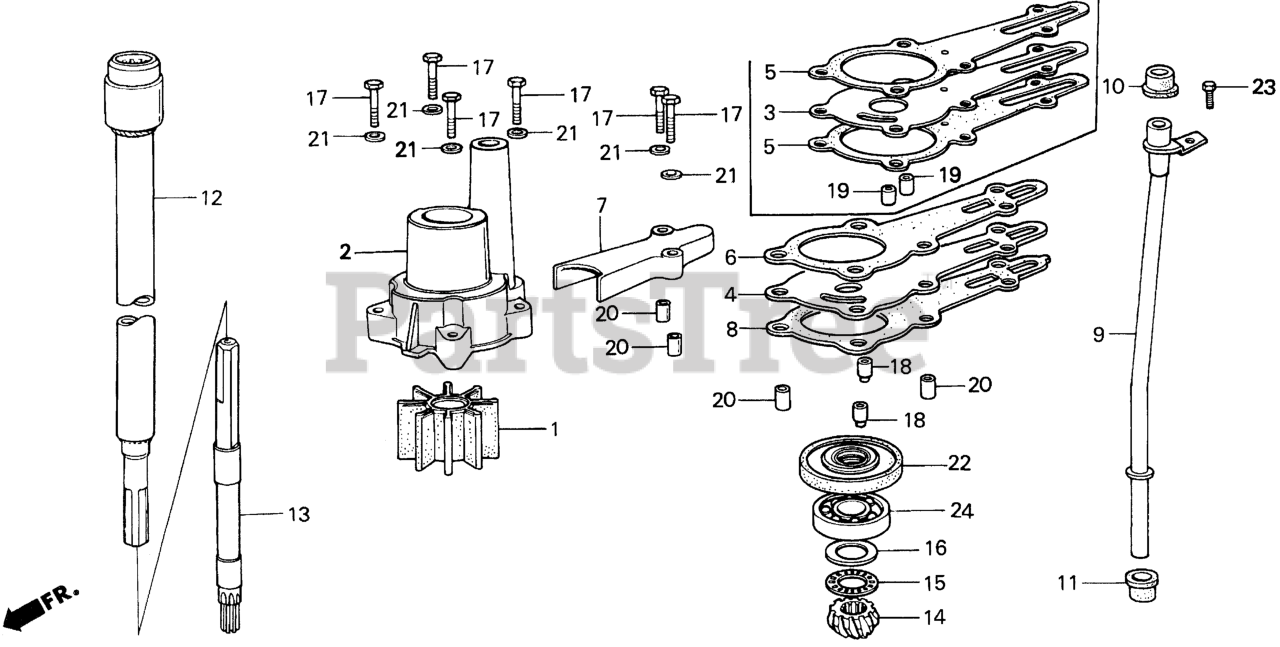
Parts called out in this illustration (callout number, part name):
1	IMPELLER, PUMP
2	HOUSING, IMPELLER
3	COVER, IMPELLER
5	GASKET, IMPELLER
7	HOLDER, IMPELLER COVER
9	TUBE, WATER (S)
10	RING, WATER TUBE SEAL
11	RING, SEAL
12	SHAFT, VERTICAL (S)
13	SHAFT, PINION
14	PINION, BEVEL
15	BEARING, THRUST (15MM)
16	WASHER A, THRUST BEARING (2.00MM)
16	WASHER B, THRUST BEARING (2.05MM)
16	WASHER C, THRUST BEARING (2.10MM)
17	BOLT, HEX. (6X28)
19	COLLAR A, DISTANCE (NOT AVAILABLE)
20	COLLAR B, DISTANCE
21	WASHER, PLAIN (6MM) Use from Frame SN 4800713.
22	SEAL, WATER (15MM) (NOK)
23	BOLT, HEX. (6X12)
24	BEARING, RADIAL BALL (6302)
